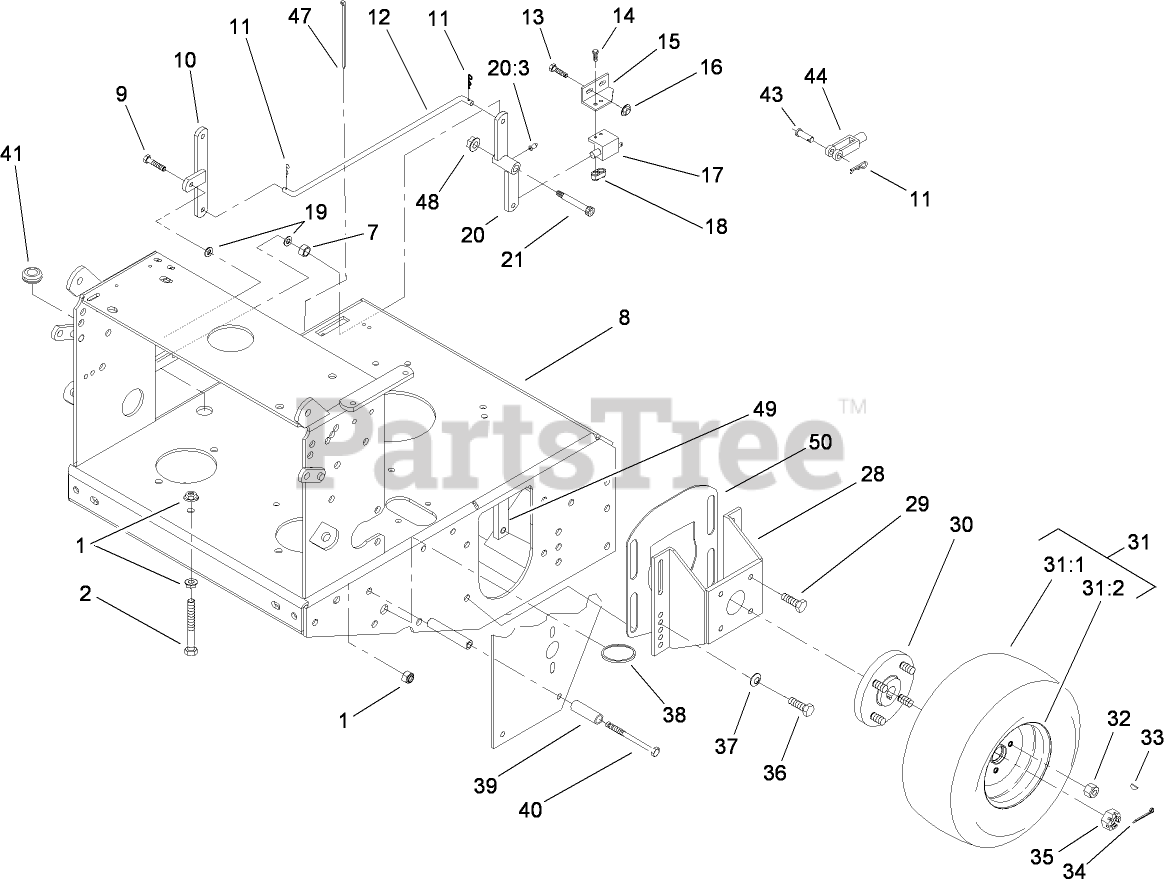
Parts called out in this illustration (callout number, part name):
1	NUT-HHF, WHIZ
2	SCREW-HH
7	NUT-LOCK, NI
8	HYDRO FRAME ASM
9	SCREW-HH
10	BELLCRANK ASM
11	PIN-COTTER
12	Linkage-Engage, Blade
13	SCREW-HH
14	SCREW-PPH
15	Bracket-Switch, Blade
16	NUT-HF
17	SWITCH-OPEN, NORMALLY
18	PLATE-TAPPED
19	WASHER-PLAIN
20	Bellcrank ASM
20:3	FITTING-GREASE, 90 DEG
28	Mount-Motor
29	SCREW-HHF
30	HUB ASM W/STUDS
31	Wheel And Tire ASM
31:1	Tire-Turfmaster
31:2	Wheel-Rim
32	NUT-LUG
33	Key-Woodruff
34	PIN-COTTER
35	NUT-HEX, SLOTTED
36	SCREW-HH
37	WASHER-BELLEVILLE
38	Ring-Split
39	SPACER-SHORT
40	SCREW-HH
41	GROMMET
43	PIN-CLEVIS
44	YOKE-ADJUSTABLE
47	TIE-CABLE
48	NUT-HF
49	BAR-NUT
50	GUARD-DEBRIS
